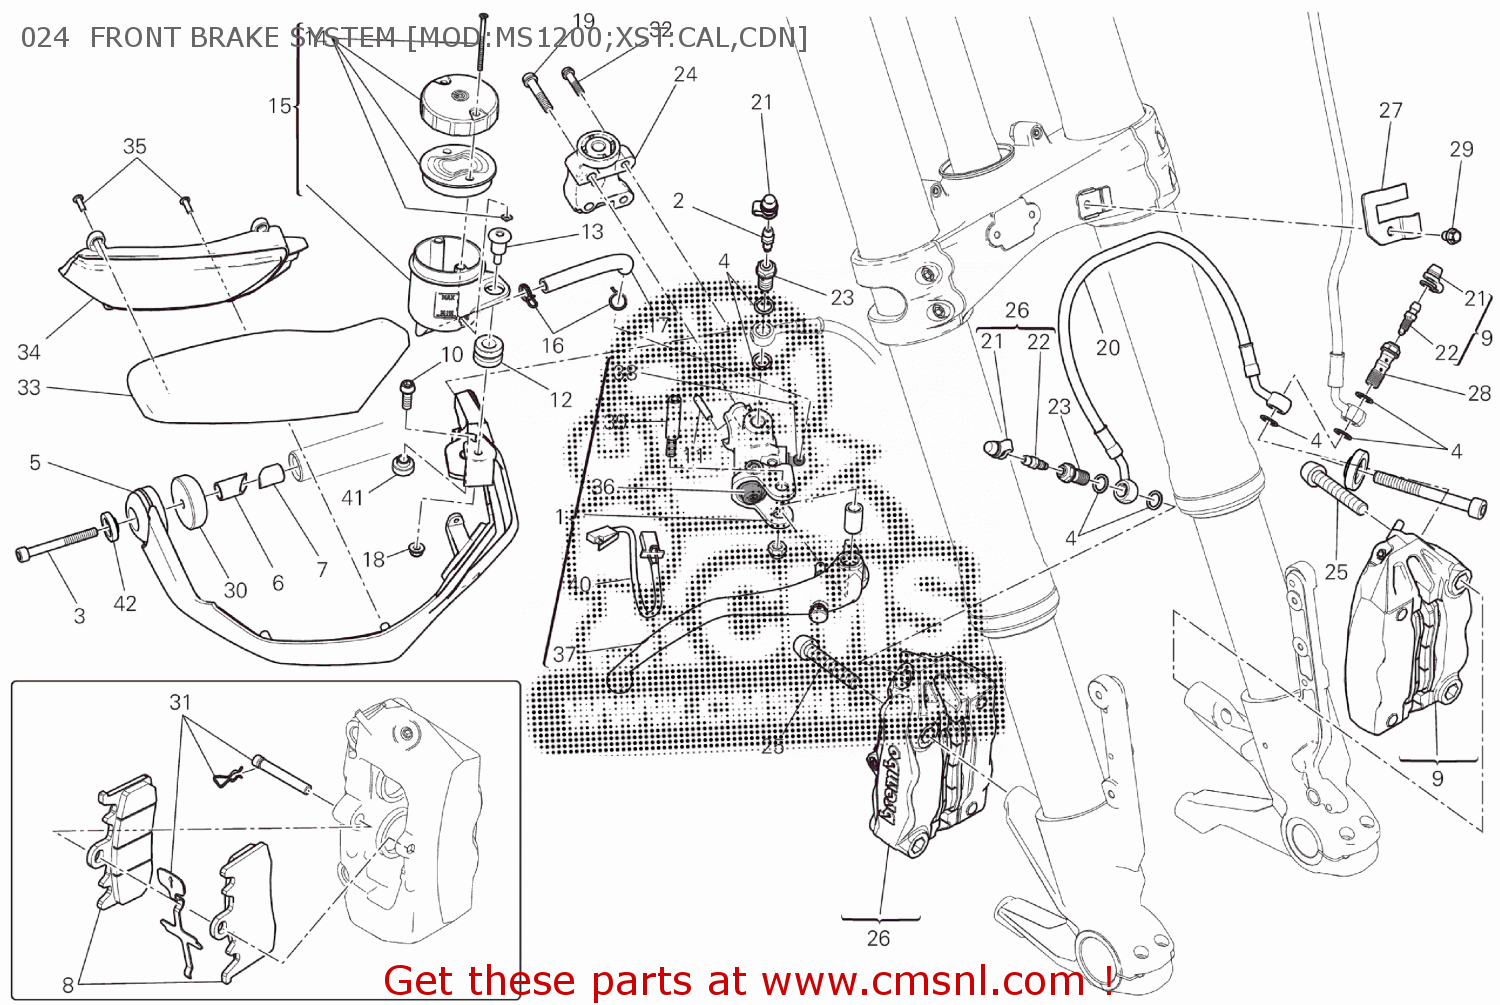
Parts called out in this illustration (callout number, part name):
1	FRONT BRAKE PUMP
2	VALVE, BREATHER
3	SCREW TCEI M6X55 UNI5931 8.8
4	WASHER 10X14X1
5	GUARD, KNUCKLE, RH
6	BUSH
7	SPINDLE, TAPER
8	PADS PAIR
9	LEFT BRAKE CALIPER
10	SCREW
11	PIN, SPRING
12	DAMPER
13	SCREW
14	CAP BRAKE FLUID TANK
15	RESERVOIR, BRAKE FLUID
16	CLAMP
17	HOSE
18	NUT
19	SCREW
20	HOSE, FRONT BRAKE CALIPER-CALIPER
21	DUST COVER
22	FRONT CALIPER DRAIN SCREW
23	BOLT, BRAKE HOSE
24	CLAMP
25	SCREW
26	RIGHT BRAKE CALIPER
27	BRACKET
28	BOLT, BRAKE HOSE
29	SCREW TEF M6X10
30	BALANCER SET, HANDLE BAR
31	SPARE PIN AND SPRING
32	SCREW TCEIF M5X20 8.8
33	GUARD, KNUCKLE, RH
34	TURN INDICATOR R.H.
35	SCREW
36	DUST COVER
37	LEVER, FRONT BRAKE
38	JOINT, HOSE
39	BOLT, LEVER
40	MICROSWITCH
41	SPACER
42	SPACER
